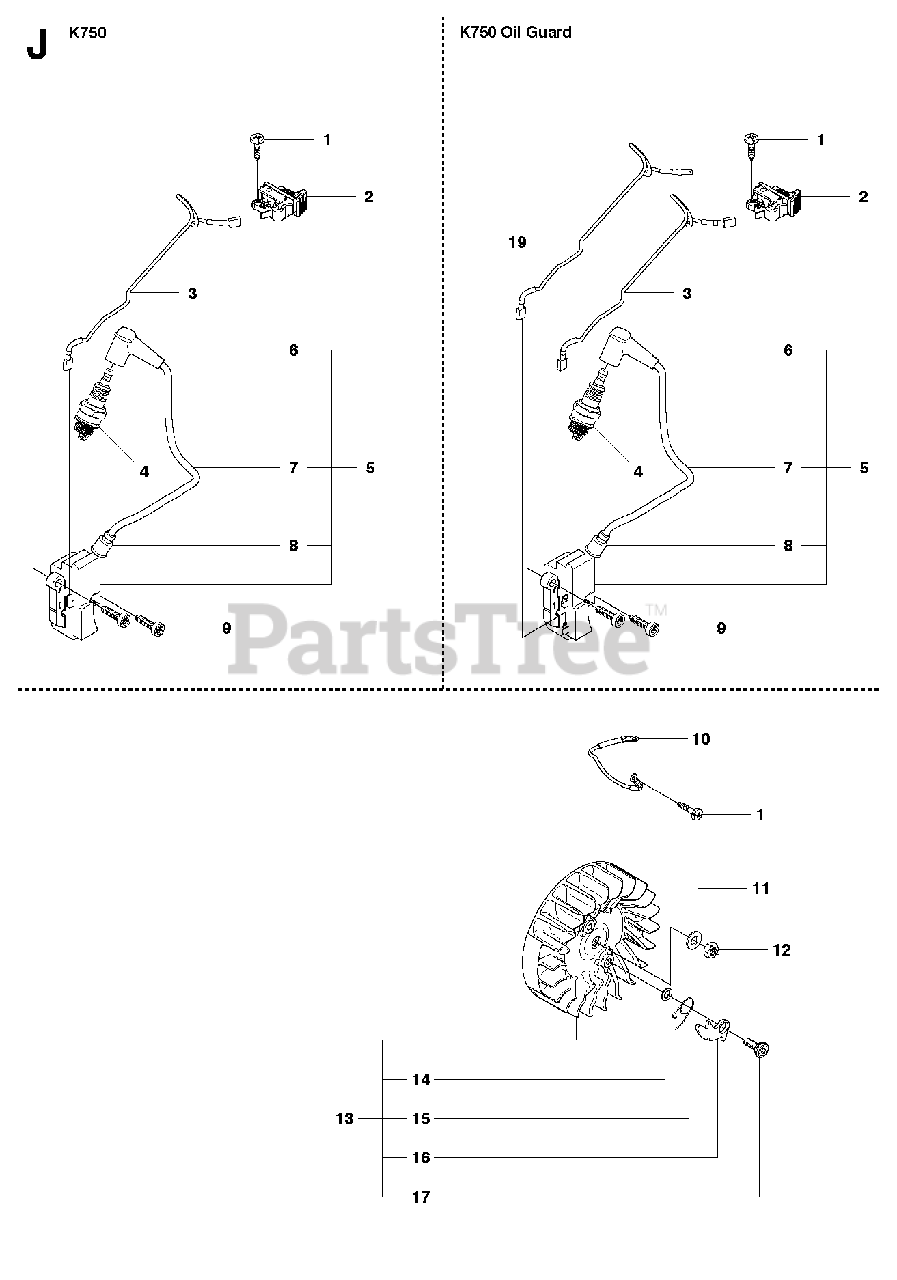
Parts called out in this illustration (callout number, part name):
1	SCREW CCRPANT
2	STOP SWITCH
3	CABLE
3	CABLEOil Guard
5	IGNITION MODULEIncl. 6 - 8
6	SPARK PLUG CAP
7	IGNITION CABLE
9	SCREW ITXSCM
13	FLYWHEELIncl. 14 - 17
17	SCREW
18	CABLEOil Guard
